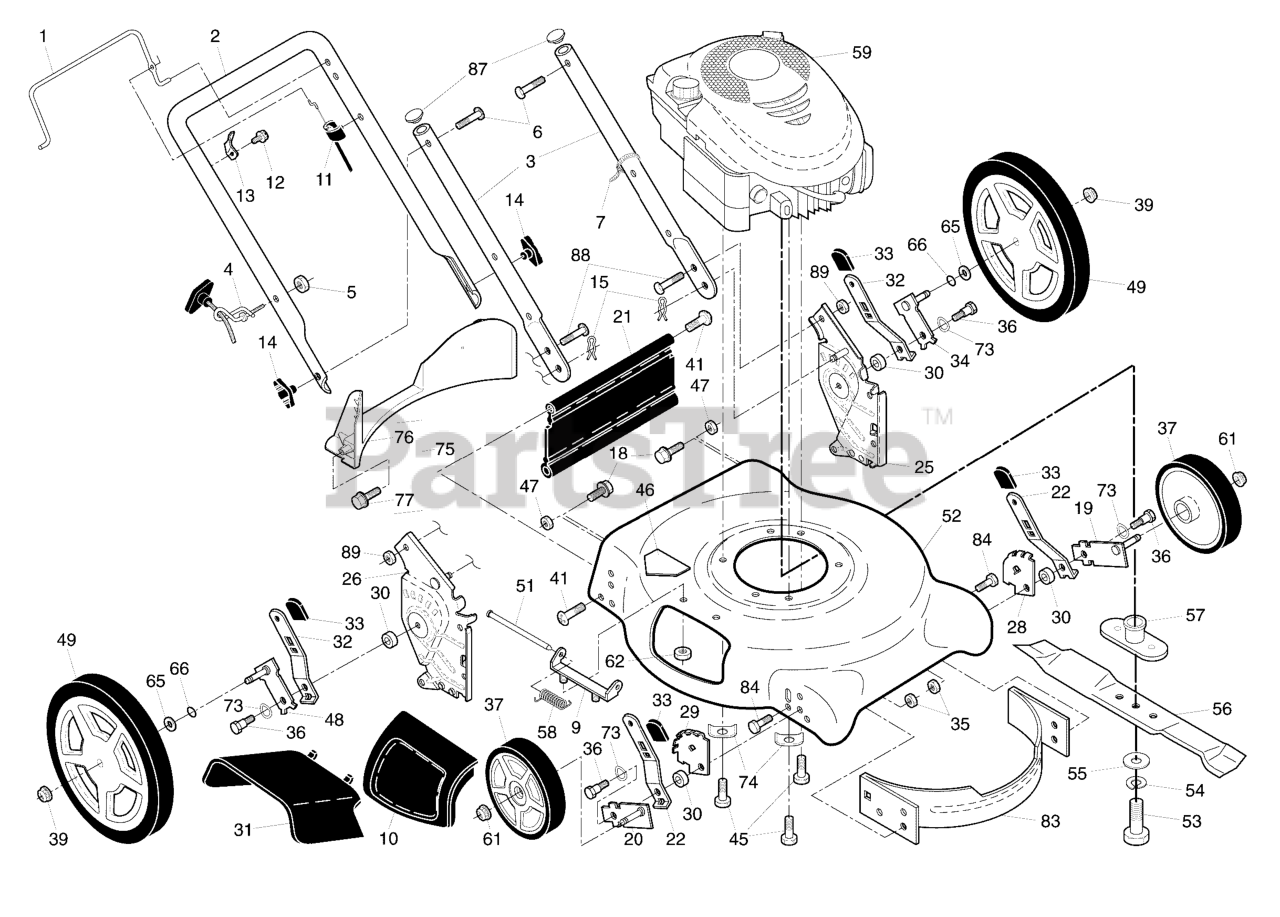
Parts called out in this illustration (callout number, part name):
1	Control Bar
2	Upper Handle
3	Bar, Lower Handle
4	Rope Guide
5	Nut, Hex
6	Handle Bolt
7	Wire Tie
9	Hinge Bracket
10	Mulcher Door
11	Engine Zone Control Cable
12	Hex Washer Head Screw
13	Up-Stop Bracket
14	Handle Knob
15	Hairpin Cotter
18	Screw 1/4-20 x 3/8
19	Axle Arm Assembly, Front, LH
20	Axle Arm Assembly, Front, RH
21	Kit, Rear Skirt
22	Selector Spring, Front
25	Handle Bracket Assy., LH
26	Handle Bracket Assy., RH
28	Wheel Adjuster Bracket, LH
29	Wheel Adjuster Bracket, RH
30	Spacer
31	Discharge Deflector
32	Selector Spring, Rear
33	Selector Knob
34	Axle Arm Assembly, Rear, LH
35	Locknut, Hex
36	Shoulder Bolt
37	Wheel & Tire Assembly, Front, 7"
39	Locknut, Hex
41	Hinge Screw
45	Screw, Hex Head, Threaded, Rolled 3/8-16 x 1
46	Danger Decal
47	Locknut, Hex 5/16-18
48	Axle Arm Assembly, Rear, RH
49	Wheel & Tire Assembly, Rear, 12"
51	Hinge Rod
52	Kit, Lawn Mower Housing
53	Screw, Hex Head, 3/8-24 x 1-3/8 Grade 8
54	Helical Lockwasher
55	Hardened Washer
56	21" Blade
57	Blade Adapter
58	Hinge Spring
59	* Engine, Briggs & Stratton
61	Locknut, Hex, Flanged
62	Locknut, Hex 1/4-20
65	Washer, Flat
66	O-Ring
73	Washer, Curved, Cylindrical
74	Washer, Special, Engine
75	Kit, Rear Baffle
76	Baffle, Rear
77	Screw, Rear Baffle
83	Baffle, Front
84	Screw, Front Baffle
87	Plug, Handle Bar
88	Bolt, Hex Head
89	Nut, Hex
